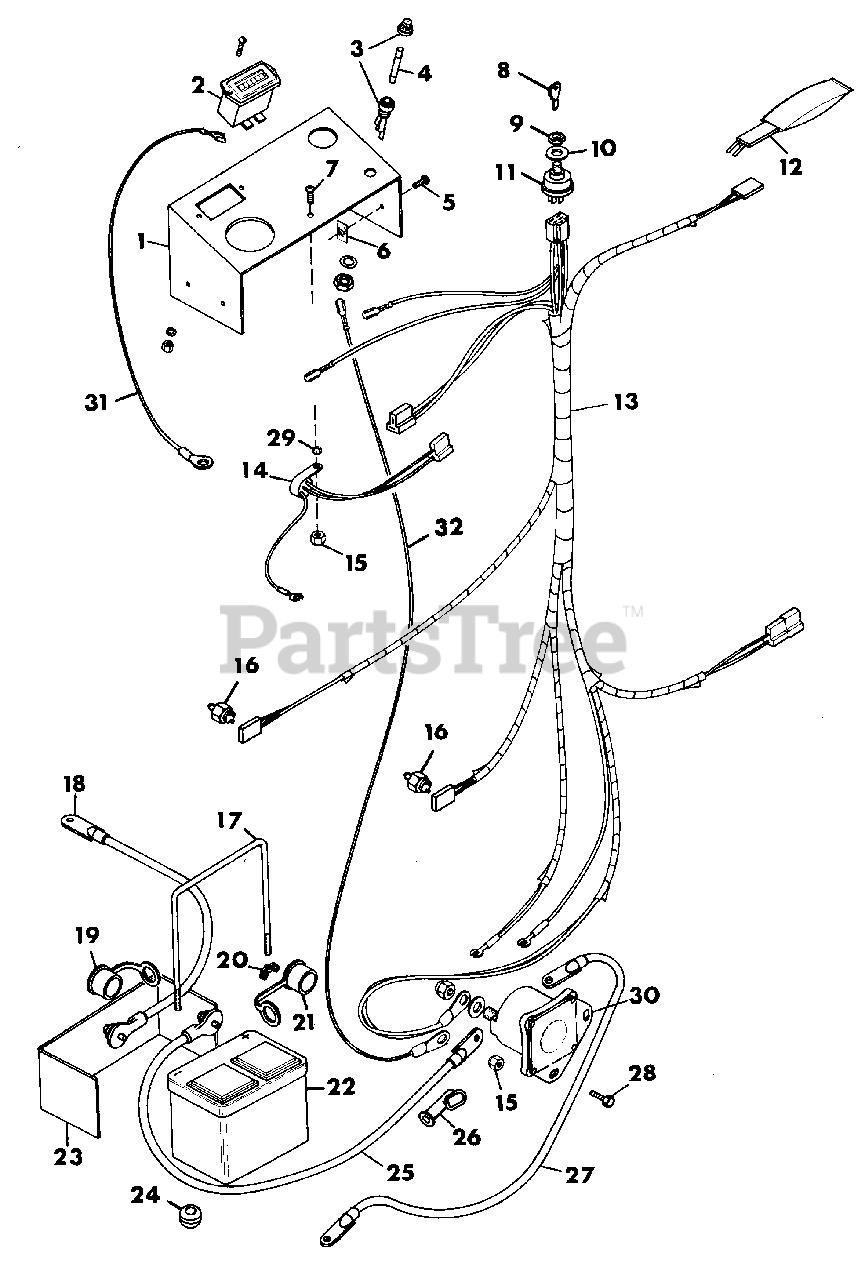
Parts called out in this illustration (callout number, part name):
1	PANEL, INSTRUMENT
2	HOURMETER
3	FUSE, PANEL
4	FUSE, 30 AMP AGC-30
5	SCREW, MACHINE 1/4-20 PAN HD
6	NUT, RETAINER
7	BOLT, HEX 1/4-20X.625
8	KEY, IGNITION SWITCH
9	NUT, JAM 9/16-24
10	WASHER, LOCK
11	SWITCH, IGNITION
12	SWITCH, SEAT
13	HARNESS, WIRING OFC
14	MODULE, INTERLOCK
15	NUT, LOCK 1/4-20
16	SWITCH, NEUTRAL START
17	ROD, BATTERY
18	CABLE, ELECTRICAL
19	COVER, BATTERY NEGATIVE TERMINAL
20	NUT, WING 1/4-20
21	COVER, BATTERY POSITIVE TERMINAL
22	BATTERY, 12 VOLT
23	GUARD, BATTERY
24	GROMMET
25	CABLE, ELECTRICAL
26	BOOT, BATTERY CABLE
27	CABLE, STARTER
28	BOLT, HEX 1/4-20X1.00
29	WASHER, LOCK 1/4 EXT TL TYA
30	SWITCH, MAGNETIC
31	WIRE, INSTRUMENT PANEL
32	WIRE, FUSE
